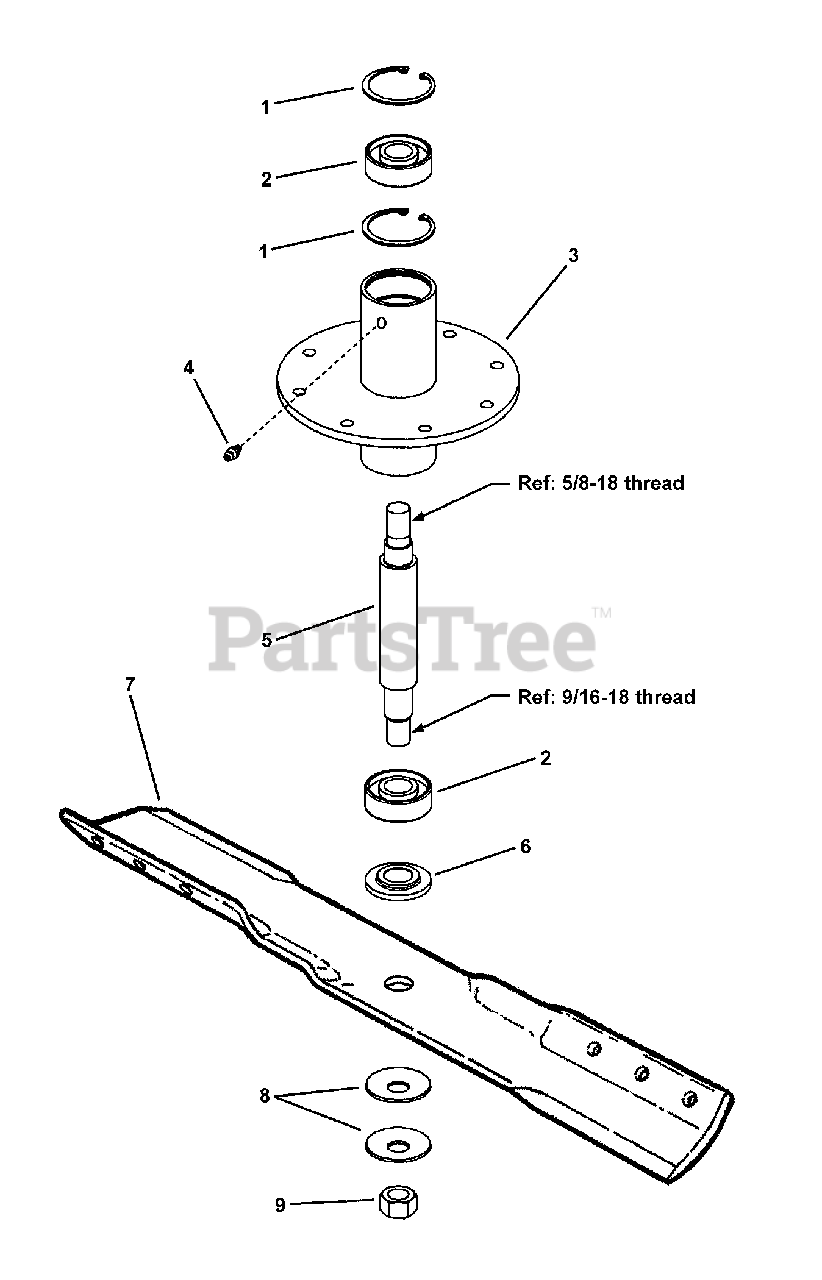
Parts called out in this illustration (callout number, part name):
1	* RING, 1-3/4" External Retaining Ring
2	* BALL BEARING, 3/4" I.D.
3	* WELDMENT, 38 Spindle Housing
4	FITTING, Lube (Press fit for .187 hole-no ball)
5	* SHAFT, Spindle (7.155" long)
6	* WASHER, Spindle Blade
7	* BLADE, 19.64 (38" Deck)
8	* WASHER, Bellville 9/16 x 1-3/4"
9	* NUT, 9/16-18 Hex, GR B
